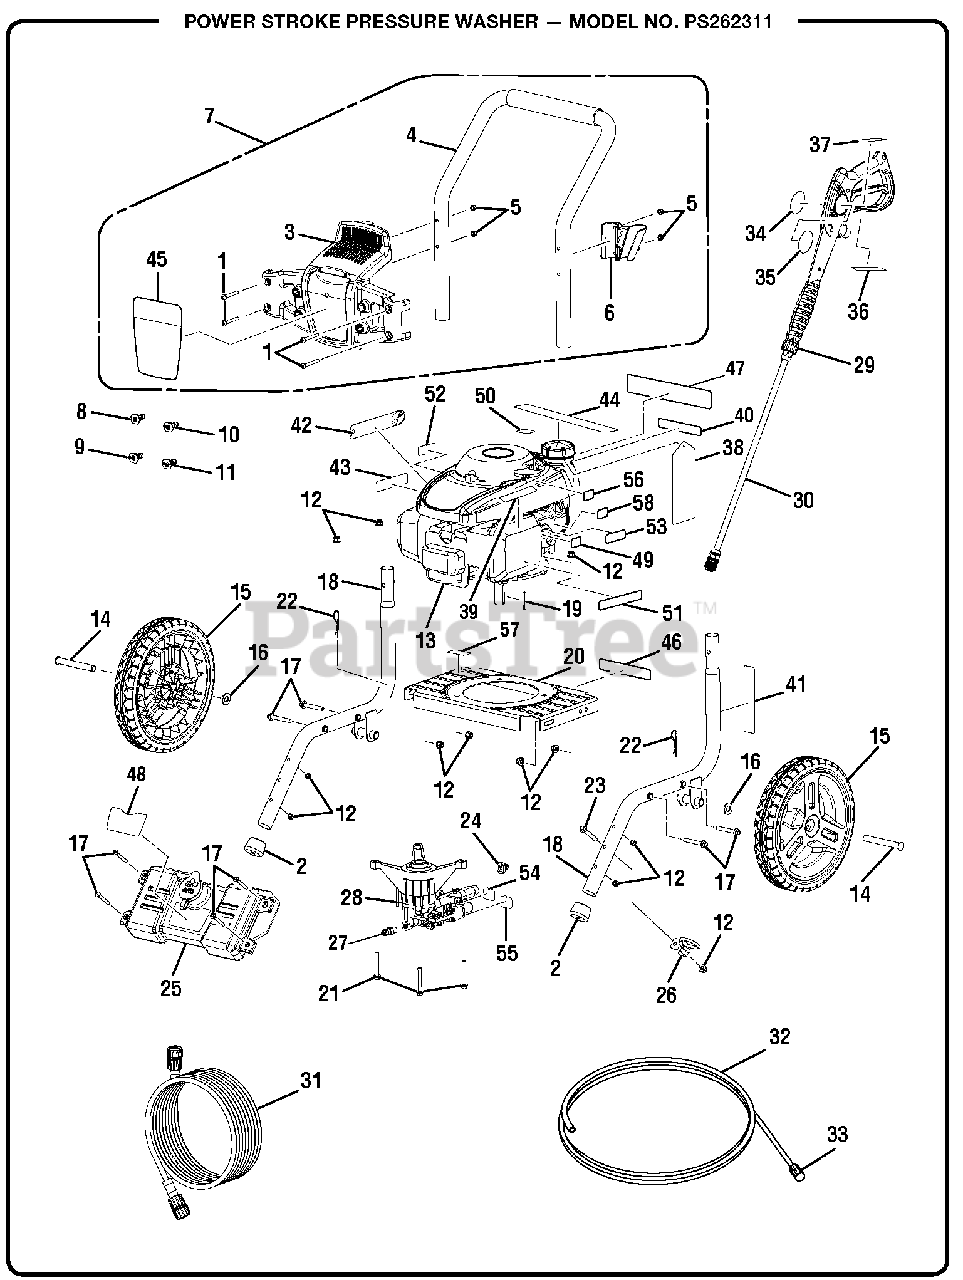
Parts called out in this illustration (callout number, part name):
1	Screw (1/4-20 x 1.85 in., T30 Torx Hd.)
2	Rubber Foot
3	Hose and Nozzle Holder Assembly
4	Handle w/Foam
5	Lock Nut (1/4-20)
6	Wand Holder
7	Handle Assembly
8	40deg Nozzle
9	Soap Nozzle
10	25deg Nozzle
11	0deg Nozzle
12	Flange Nut (M8 x 1.25)
13	Engine
16	Washer (1/2 in.)
17	Bolt (M8 x 55 mm, Flange Hd.)
18	Main Frame Assembly
19	Output Shaft Key (3/16 in. x 40 mm)
20	Engine Plate
21	Bolt (M8 x 60 mm, Flange Hd.)
22	Axle Clip
23	Bolt (M8 x 50 mm)
24	Filter Screen (Pump Inlet)
25	Soap Tank with Cap
26	Wand Holder Loop
27	Thermal Release Valve
28	Pump
29	Trigger Handle Assembly
30	Extension Wand
31	Hose (25 ft., 3000 psi)
32	Chemical Siphon Tube
33	Chemical Siphon Filter
34	Label (Wand Logo)
35	Label (Wand Warning)
36	Fr/Sp Label (Wand Warning)
37	Label (Wand Rating)
38	Danger Hangtag
39	Engine Quick Start Label
40	Combustion Label
41	Pump Quick Start Label
42	Add Oil Hangtag
43	Hot Surface Label
44	No Oil Label
45	Performance Label
46	Data Label
47	Danger Label
48	Soap Tank Label
49	Engine On/Off Label
50	No E85 Label
51	Inquiries Label
52	Lubricant Label
53	Choke/Run Label
54	Garden Hose Hang Tag
55	High Pressure Hose Hang Tag
56	Recoil Start Label
57	Oil Fill Location Label
58	Choke Label
